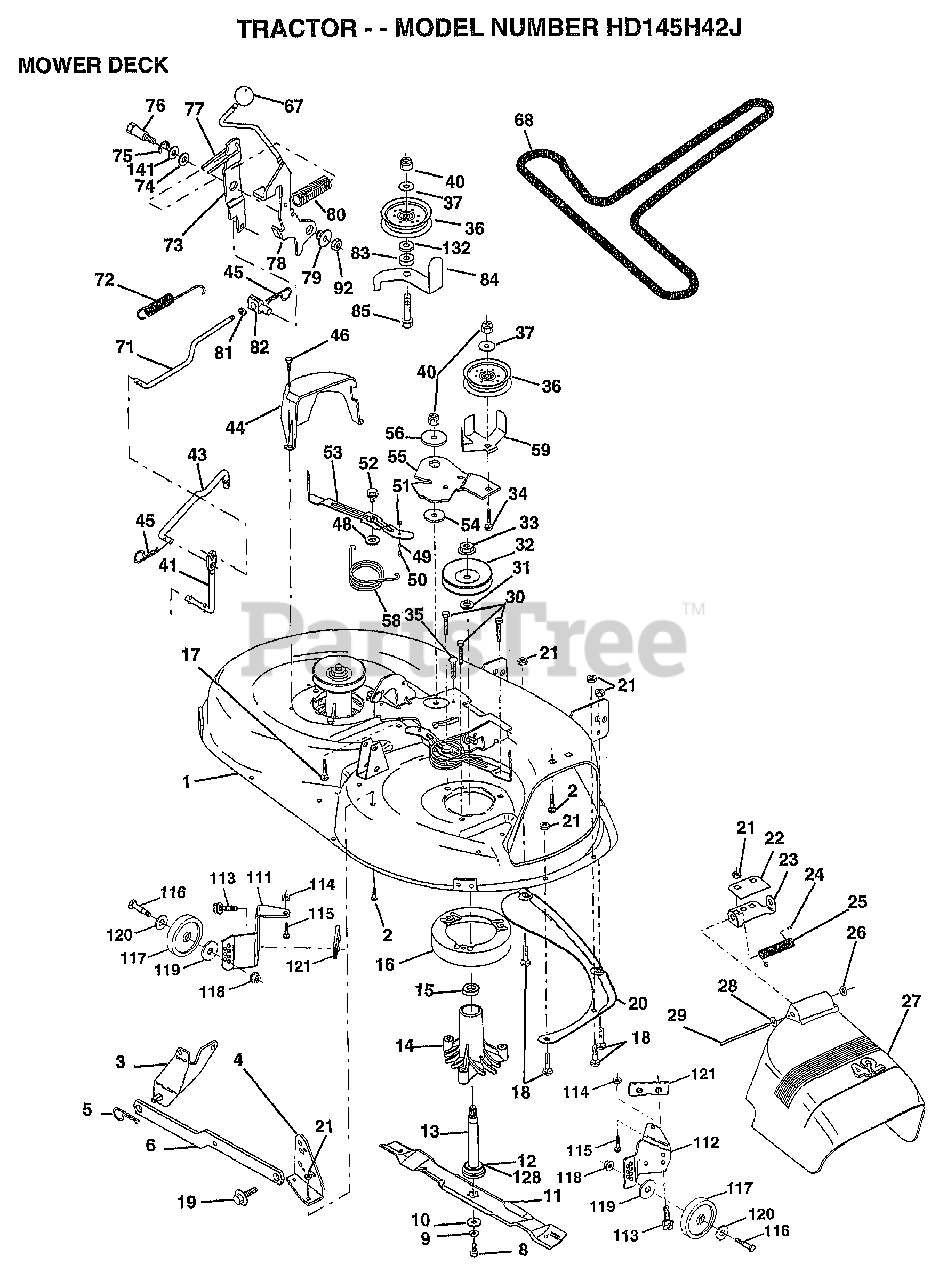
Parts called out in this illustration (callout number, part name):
1	"HOUSING ASSY.42"""
2	BOLT
3	BRKT ASM SWAY BAR
4	BRKT DECK SW BAR
8	BLADE BOLT
10	WASHER.HARD.BLADE
11	"BLADE.42"" HIPERF"
12	BEARING.BALL
14	HSG ASM MANDREL
15	BEARING
16	STRIPPER RND MWR
17	BOLT RDHD 3/8-16
18	BOLT
19	BOLT SHD 5/16-18
20	BAFFLE VORTEX 42
22	STIFFENER BRKT
23	DEFLECTOR BRKT
24	CAP-SLEEVE LT
25	SPRING TORSION
26	NUT PUSH M
27	DEFLECTOR.SHIELD
28	WASHER
29	HINGE ROD
30	"SCREW-THD ROLL,WA"
31	WASHER
32	PULLEY.MANDREL.42
34	BOLT
35	XMAS TREE FASTNER
36	FLAT IDLER PULLEY
37	WASHER
41	PIVOT ROD
43	ROD CLUTCH W/NIBS
44	GUARD MAND LH BLK
45	RETAINER M
46	SCREW.1/4-20X5/8
48	HARD SMALL WASHER
49	ROLLER ASM-CAM
50	SHOULDER BOLT
51	LOCKNUT
52	BOLT.SHLD.5/16-18
53	BRAKE PAD ARM ASM
54	HARDENED WASHER
55	ARM-IDLER
56	SPACER RETAINER
58	SPRING TORSN BRAK
59	GUARD IDLER TUV
67	KNOB.RD.7/16-14
68	BELT.V.T-PATH
71	ROD CLUTCH 38/42
72	RETURN SPRING
73	CLUTCH ARM SECOND
74	WASHER
75	RING
76	SHOULDER BOLT
77	SPRING KEEPER
78	LEVER.ASM.CLUTCH
79	BUSHING
80	SPRING.CLUTCH.MWR
81	NUT
82	TRUNION ADJ
83	WASHER
84	"KEEPER-BELT,FIXED"
85	BOLT
92	NUT
111	BRACKET.GWHL.LH.
112	BRACKET.GWHL.RH.
113	SCREW
116	BOLT M
117	WHEEL.GAGE.BLK.PL
118	LOCKNUT
119	WASHER
120	WASHER
121	BRACKET.EXTRD.GWL
128	WASHER.FELT.
132	WASHER GT
141	WASHER .T
